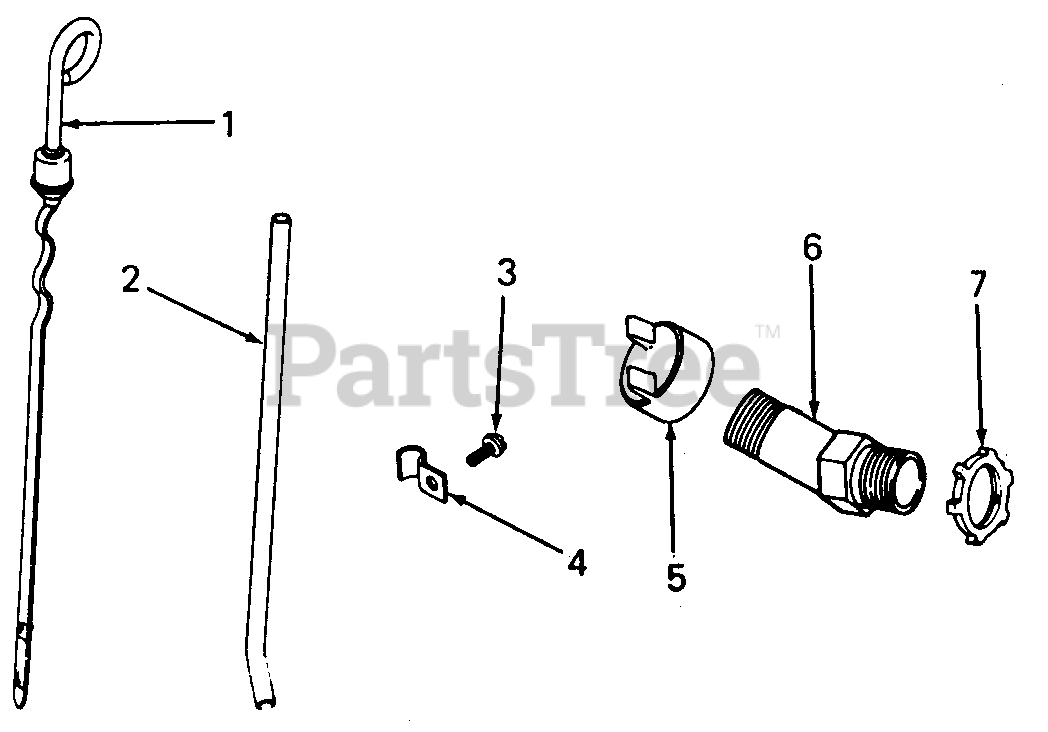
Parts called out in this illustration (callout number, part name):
1	Dipstick, Oil Level, 11-5/16"
2	Tube, Oil Level, 7-11/16"
3	Screw, Hex Wash Hd, #10-32 X 3/8
6	Tube, Oil Fill
7	Nut, Lock, 3/4 IP
